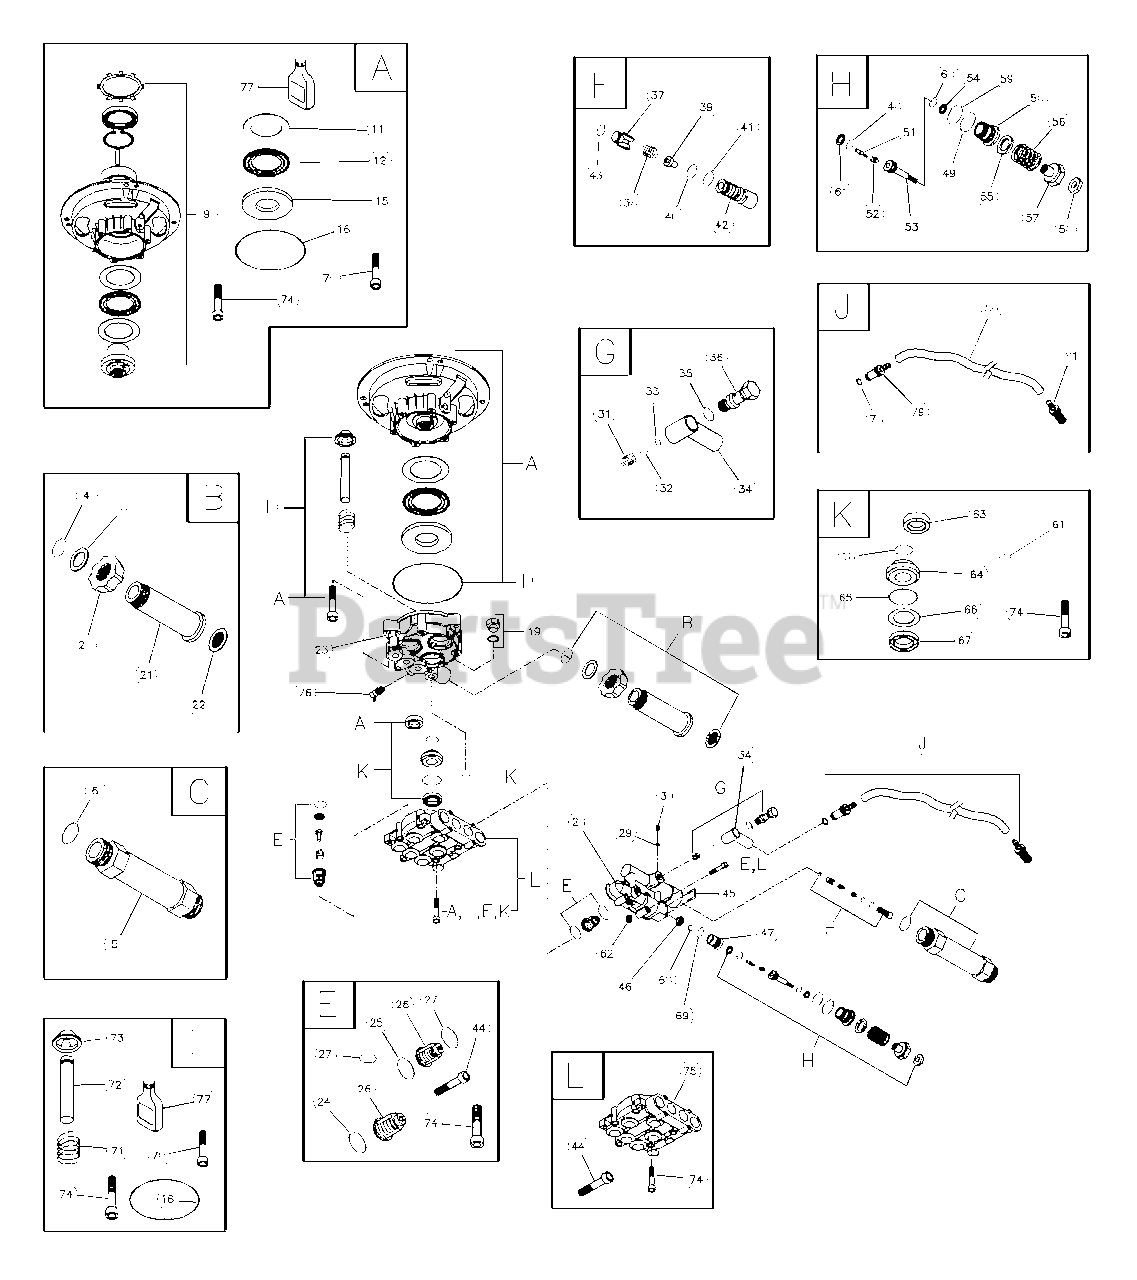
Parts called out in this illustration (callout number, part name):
4	O-RING
5	OUTLET EXTENSION
6	O-RING
8	WASHER
9	ASSY, Engine Adapter
11	FLAT BEARING DISC
12	ROLLER BEARING
15	FLAT BEARING DISC
16	O-RING
18	O-RING
20	GARDEN HOSE w/ FINGER GRIP
21	EXTENSION, INLET
22	WASHER w/ FILTER
24	O-RING
25	O-RING
26	ASSY, Valve Group
27	O-RING
29	O-RING
30	SCREW
31	SPRING
32	BALL
33	O-RING
34	CONNECTION, Chemical Inlet
35	O-RING
36	SCREW, Fitting
37	VALVE, Non-Return
38	SPRING
39	INJECTION NOZZLE
40	O-RING
41	O-RING
42	INJECTION NIPPLE
43	O-RING
44	SCREW
46	VALVE, Seat Plate, Brass
47	VALVE, Seat, Stainless
48	BACK RING
49	O-RING
50	VALVE, By Pass, Brass
51	PISTON
52	SPRING, Easy Start
53	PISTON, Body
54	RING, Back
55	SPACER
56	SPRING, Regulation Press
57	NUT, Regulation Press
58	NUT
59	O-RING
60	O-RING
61	O-RING
63	SEAL
64	PILOT SPACER, Brass
65	O-RING
66	WASHER
67	SEAL, H.P.
68	BALL, Stainless Steel
69	O-RING
70	SCREW
71	SPRING
72	PISTON, Stainless Steel
73	SPRING PLATE
74	SCREW
75	HEAD, Pump
76	THERMO RELIEF
77	OIL BOTTLE
78	O-RING
79	TUBE, Inlet Support
80	TUBE, Chemical
81	FILTER
A	KIT, WOBBLE PLATE BEARING
B	KIT, WATER INLET, ALUM
C	KIT, OUTLET, ALUM
D	KIT, PISTON
E	KIT, CHECK VALVES
F	KIT, INLET CHECK
G	KIT, CHEMICAL INJECTION
H	KIT, UNLOADER STEM
J	KIT, CHEMICAL HOSE
K	KIT, SEAL SET
L	KIT, HEAD BRASS
